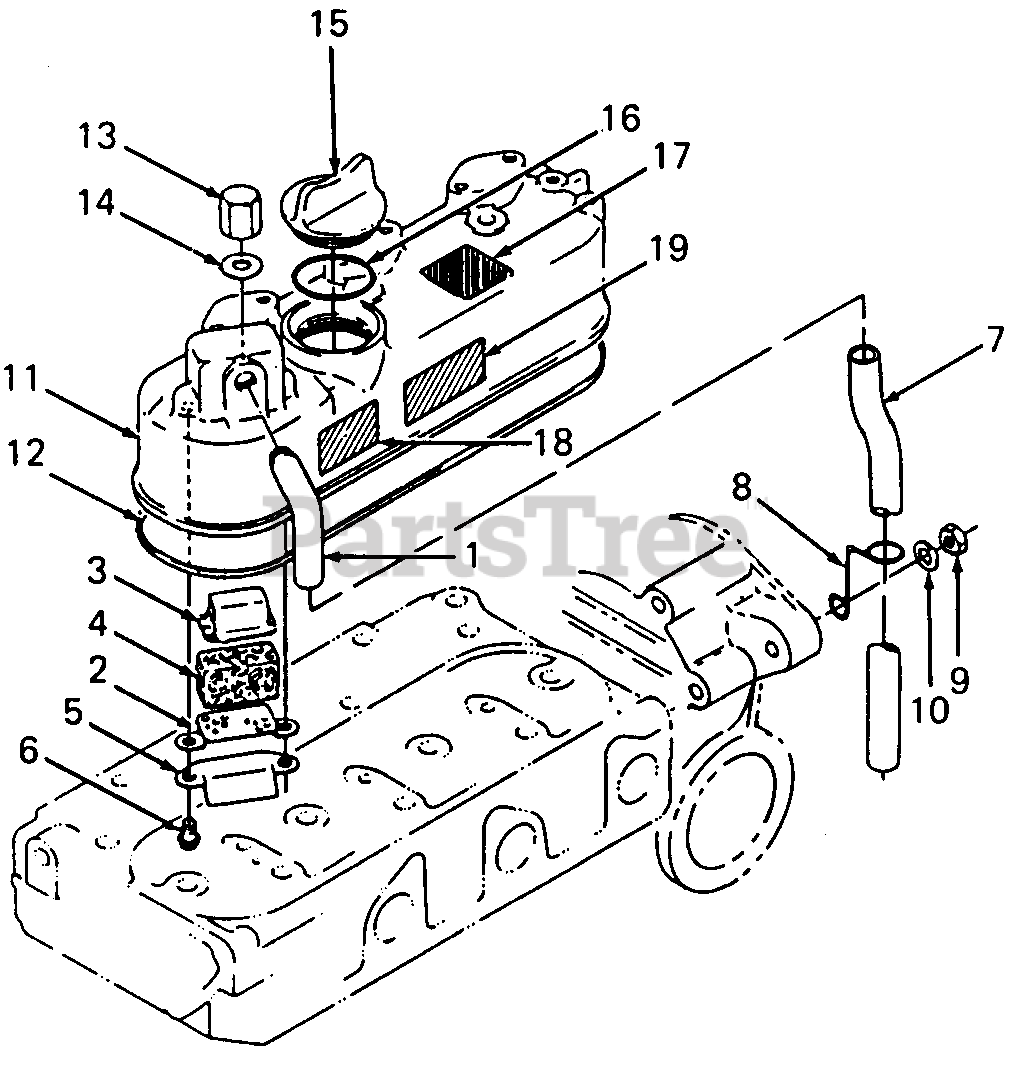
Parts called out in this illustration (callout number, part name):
1	Joint, Breather Pipe
2	Plate, Breather Element-1
3	Plate, Breather Element-2
4	Element, Breather
5	Breather, Oil Shield
6	Screw w/Washer
7	Pipe, Breather
10	Washer, Plain
11	Cover, Cylinder Head
12	Gasket, Head Cover
15	Plug
18	Label, Ether Caution
19	Label, Antifreeze
